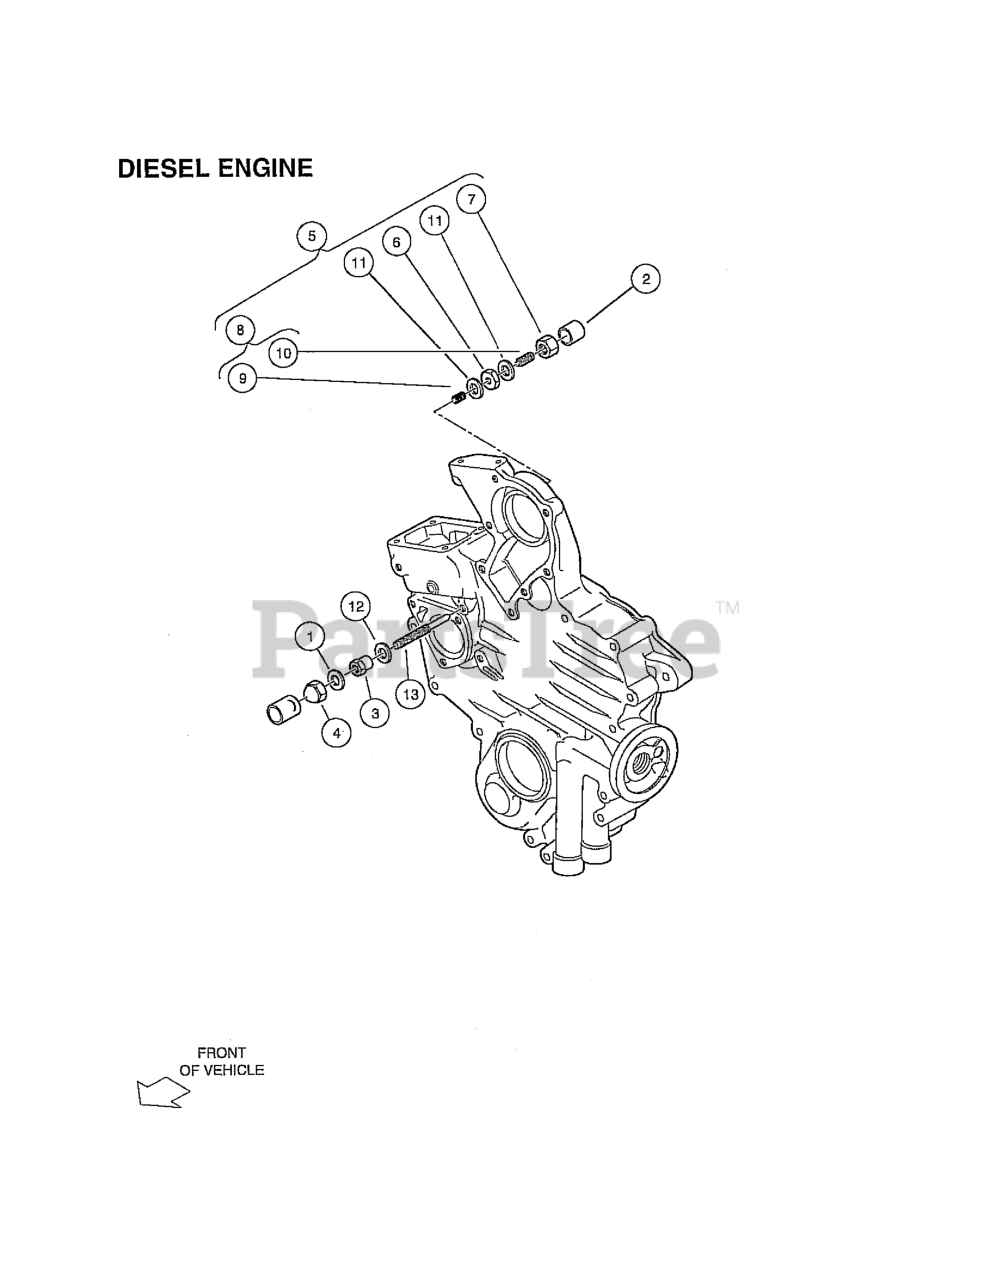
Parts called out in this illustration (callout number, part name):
1	GASKET, 6X10
2	CAP, BOLT ASSY
3	NUT, LOCK, SPECIAL
4	NUT, SPECIAL
5	ASSY,IDLE APPARATUS
8	ASSY, BOLT, ADJUSTING
9	SPRING, IDLE APPARATUS
11	GASKET, IDLE APPARATUS, REAR
12	GASKET, IDLE APPARATUS, FRONT
13	BOLT-IDLE ADJUSTING
